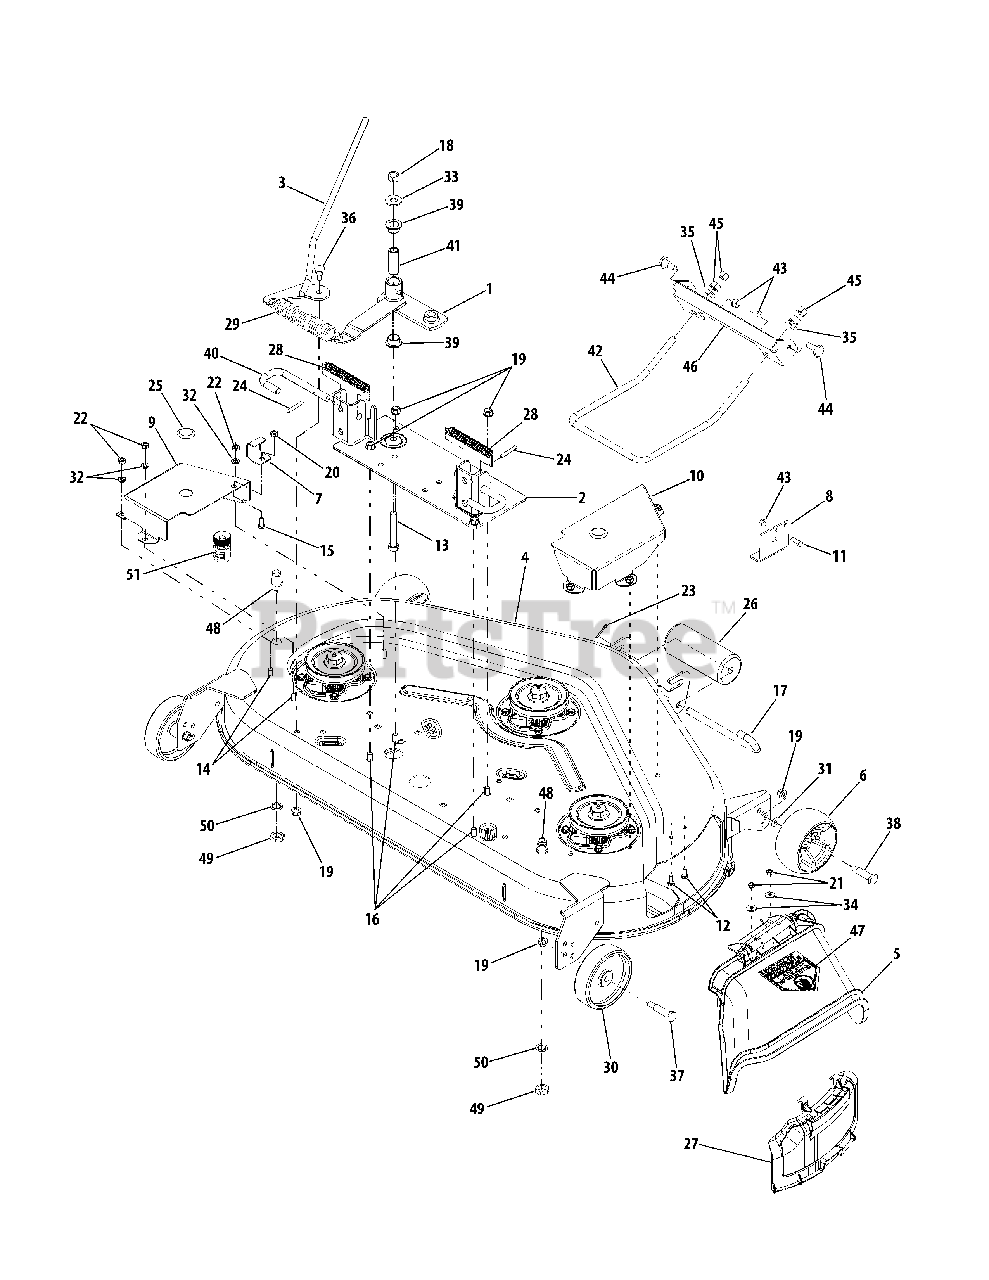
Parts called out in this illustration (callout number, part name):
1	Idler Assembly
2	Plate Assy, Mounting
3	Handle, Tension
4	Deck Housing Assembly
5	Chute Assembly
6	Wheel, Deck Ball
7	Bracket, Stop
8	Bracket, Up-Stop
9	Belt Cover, LH
10	Belt Cover, RH
11	Screw, Hex Cap, 3/8-16 x1.0 Gr5
12	Screw, Hex Cap, 1/4-20 x .62
13	Screw, Hex Cap, 1/2-20 x 3.0
14	Screw, Self Tap, 5/16-18 x .75
15	Screw, Hex Cap, 5/16-18 x .75
16	Bolt, Carriage, 3/8-16 x .75 GR5
17	Pin, Roller, 1/2 Dia x 7.31
18	Nut, Hex Lock, 1/2-20
19	Nut, Flange Lock, 3/8-16
20	Nut, Flange Lock, 5/16-18
21	Nut, Hex, 1/4-20 GR5
22	Nut, Hex, 5/16-18, GR5
23	Pin, Cotter, 1/8 Dia x 1
24	Pin, Spiral Spring, 3/16 Dia x .75
25	Button Plug
26	Front Roller
27	Plug, Mulch
28	Spring, Comp, .66 OD x 1.8
29	Spring, Ext, .162 Dia x 1.25 OD
30	Wheel, Deck, 5.0 x 1.38
31	Washer, Belleville, .401 x .870 x .63
32	Washer, Lock, 5/16
33	Washer, Flat, 1/2 x 1.25 x .10
34	Washer, Bell, .265 x .75 x .062
35	Washer, Flat, .531 x 1.062 x .134 HT
36	Bolt, Shoulder, .498 Dia x .340
37	Screw, Shoulder, 496 x 1.525:3/8-16
38	Bolt, Shoulder, .496 x 2.5 : 3/8-16
39	Bearing, Flange, 3/4 ID x .52 LG
40	Pin, Mower Support
41	Spacer, .5 OD x .75 x 2.07 Lg
42	Rod, Front Lift
43	Nut, Flange Lock, 3/8-16 GrF
44	Bolt, Shoulder, .50 Dia. x .494 Lg
45	Nut, Hex, 1/2-13 Gr5
46	Bracket, Front Lift
47	Graphic, Danger
48	Nozzle, Deck Wash
49	Nut, Hex M16-1.5
50	Washer, Lock
51	Adapter, Water Nozzle
